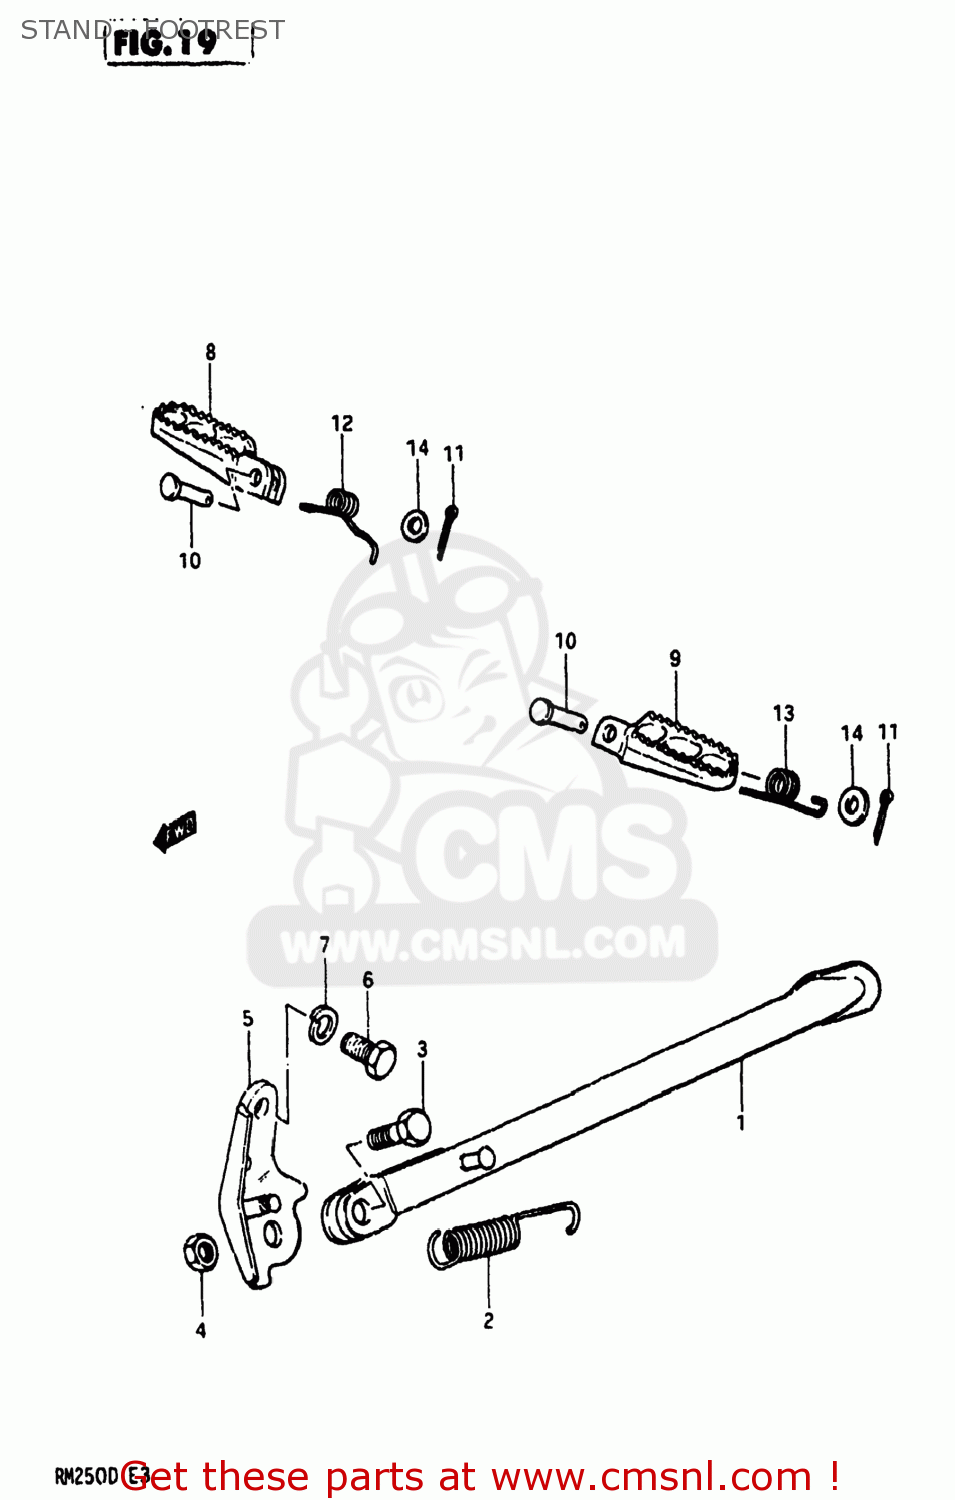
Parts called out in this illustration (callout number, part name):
1	STAND,SIDE
2	SPRING
3	BOLT(10X30)
4	NUT
5	BRACKET,SIDE STAND
6	BOLT(10X19)
7	LOCK WASHER
8	FOOTREST,RIGHT
9	FOOTREST
10	PIN
11	PIN 20X20
12	SPRING
13	SPRING,FOOTREST,LEFT
14	WASHER
